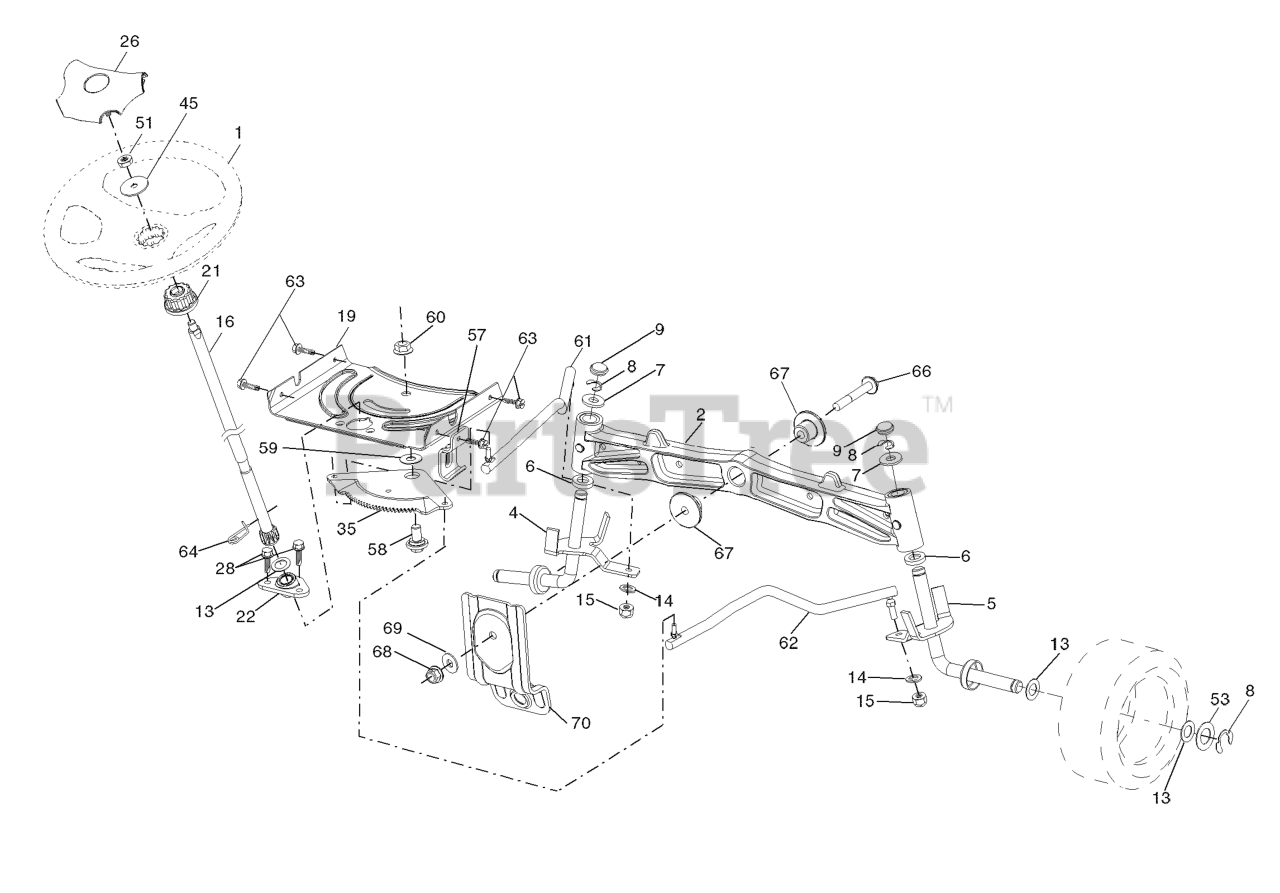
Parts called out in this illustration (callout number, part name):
1	RP WHEEL.STEER.HUSQ.PREM.OVMLD
2	AXLE.CAST.IRON
4	SPINDLE.WELDED.LH.16"TEX
5	SPINDLE.WELDED.RH.16"TEX
6	THRUST WASHER
9	CAP.SPINDLE.BLACK
14	WASHER, LOCK 3/8
15	NUT CROWNLOCK 3/8-24
16	SHAFT, STEERING
19	PLATE.STEER.DDL.NLT/NG
21	ADAPTER, WHEEL STNG..
22	BUSHING.ASM.STEERING.A
26	RP INSERT.CAP.WHL.STRG.HUSQ.
28	SCREW, 3/8-16X3/4
35	GEAR.SECTOR.PLATE.DDL.
45	WASHER 9/16"ID, 2 3/8"OD
51	NUT.HEX.1/2-20
53	WASHER.HARDENED
57	BRKT.UPSTOP.GT/LT.TEX
58	BOLT.SHOULDER.SECTOR.P
59	WASHER.THURST.SECTOR.S
60	NUT FLANGE LOCK 5/8-11
61	DRAGLINK.LH.BALLSTUD.D
62	DRAGLINK.RH.BALLSTUD.D
63	SCREW
64	RETAINER.CLIP.SPRING.S
66	BOLT HEX FGHD 7/16-14 X 3 SERR
67	BUSHING.PM.FRONT AXLE
68	NUT.LOCK.FLANGE.7/16
69	WASHER.1.5X.505X.118
70	BRKT.DECK.SUSPENSION.F
